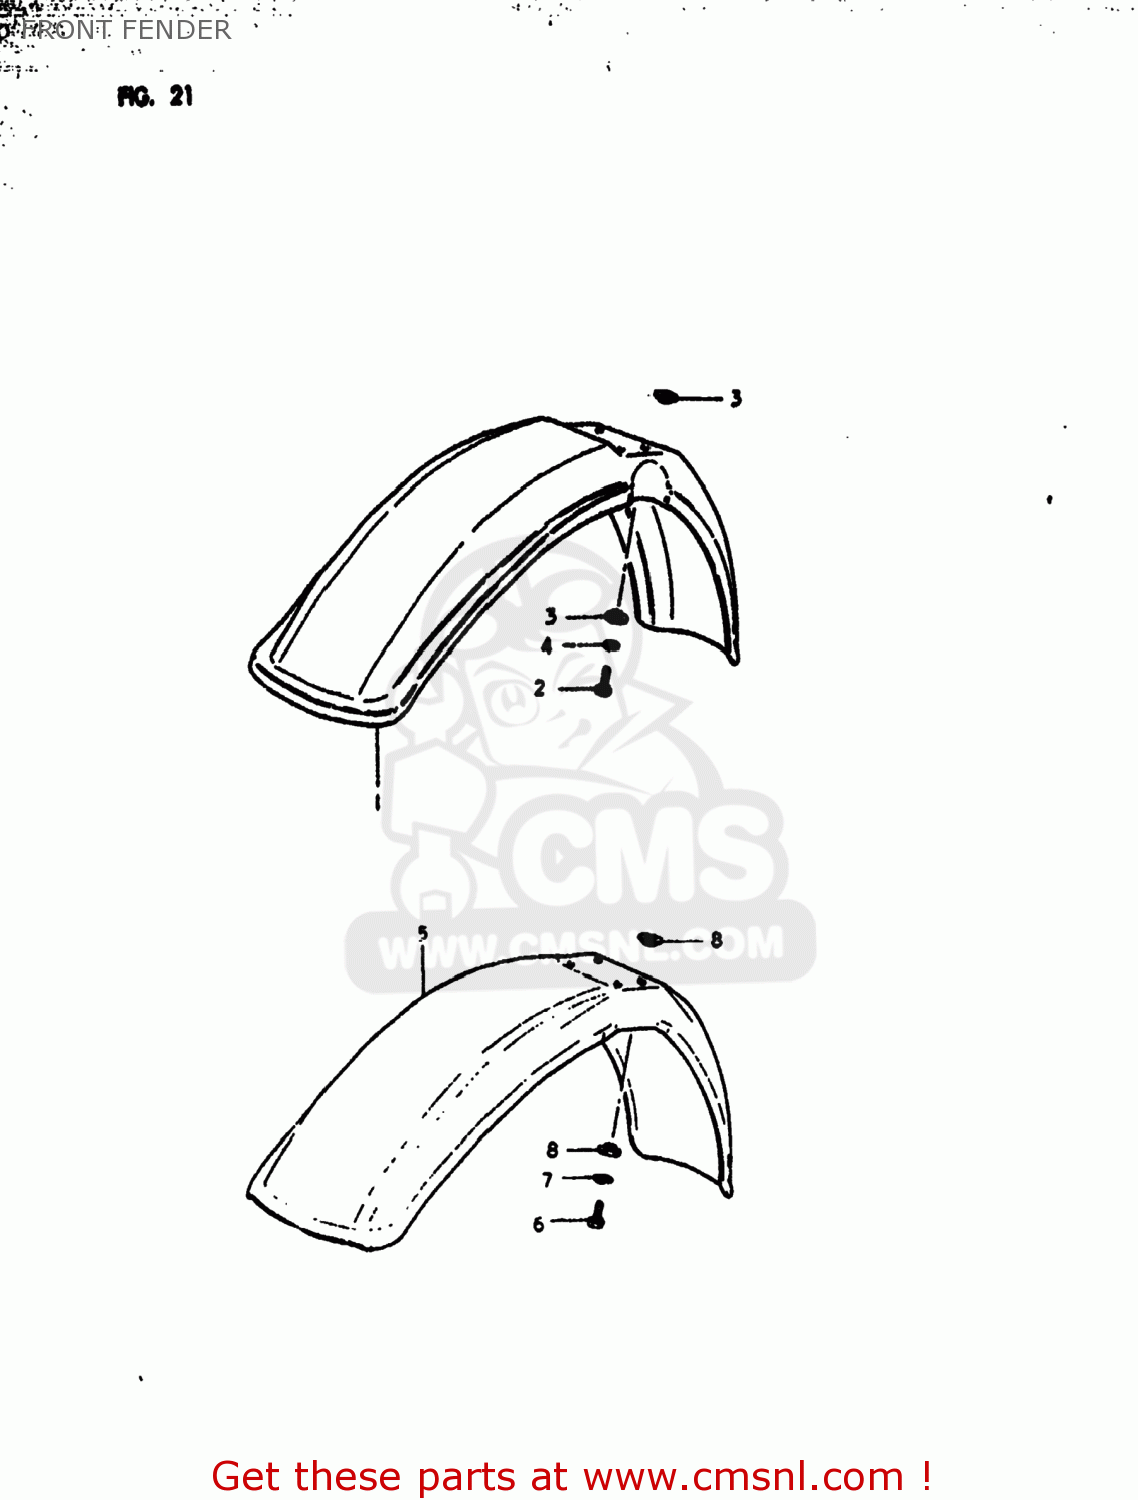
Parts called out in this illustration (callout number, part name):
1	FENDER,FRONT
2	BOLT, UPPER
3	SPACER
4	LOCK WASHER
5	FENDER,FRONT
6	BOLT, UPPER
7	LOCK WASHER
8	WASHER
